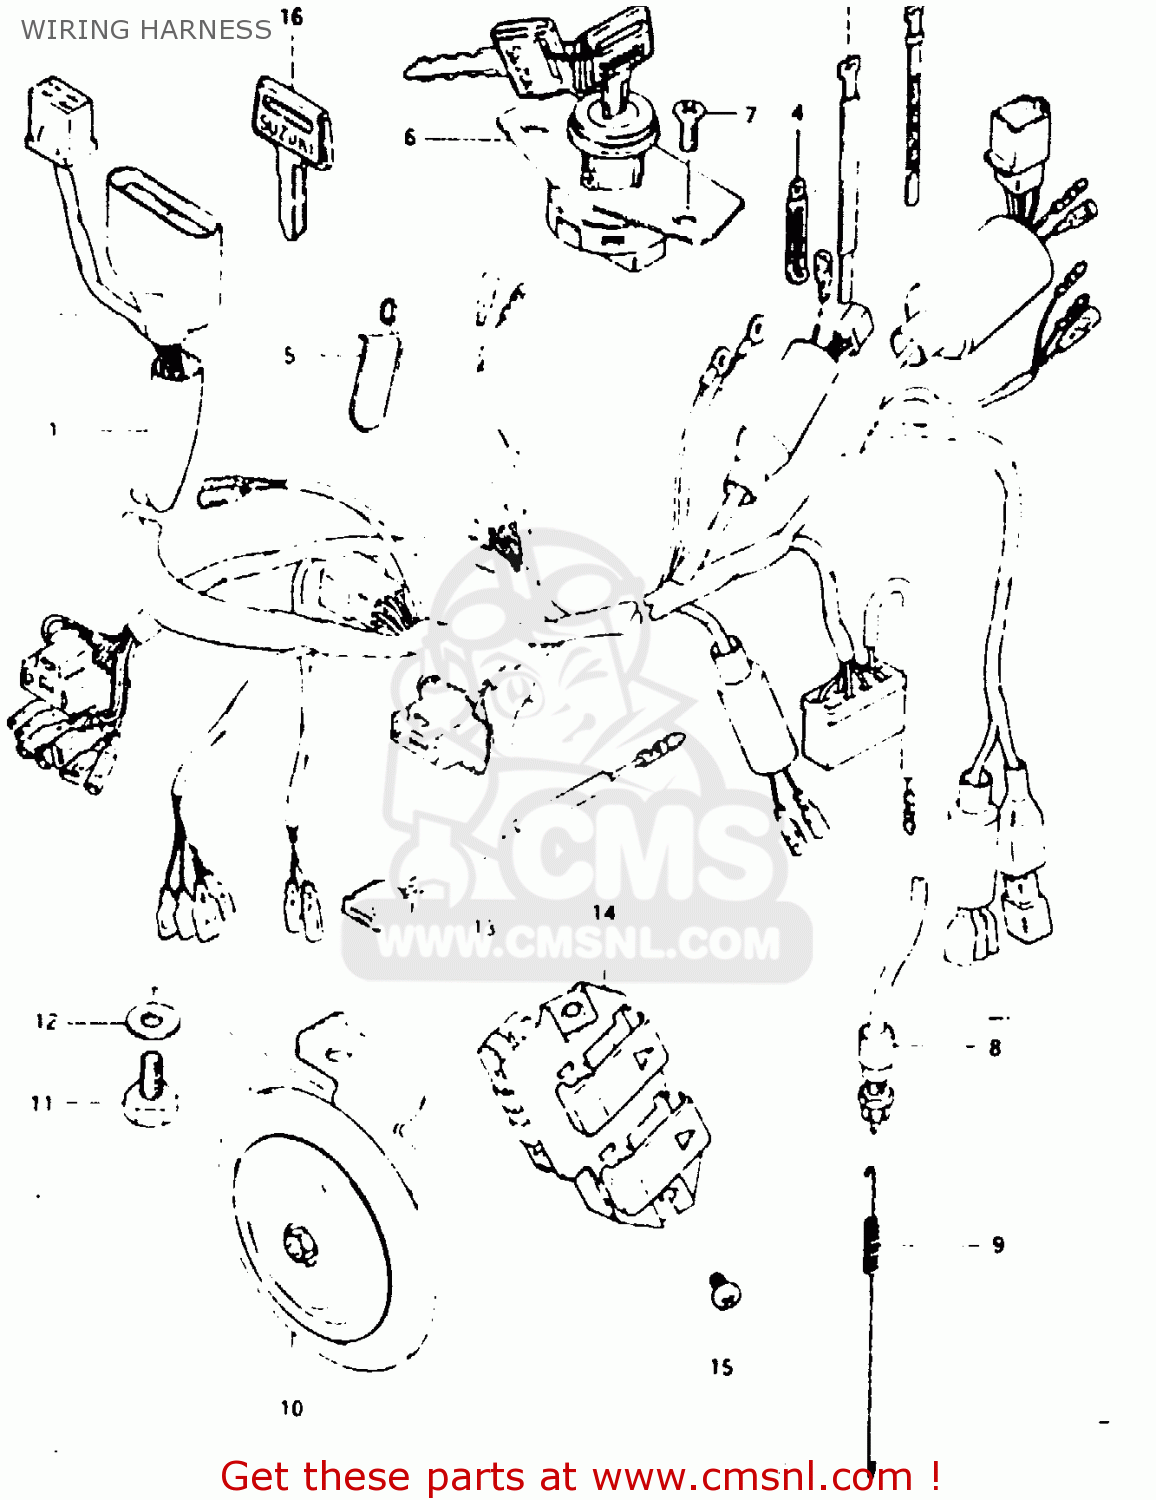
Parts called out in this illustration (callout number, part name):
1	WIRING HARNESS
2	CLAMP
3	CLAMP(L:80)
4	CLAMP
5	BOOT,WIRING HARNESS
6	SWITCH ASSY,IGNITION
7	SCREW
8	SWITCH ASSEMBLY,STOP LAMP
9	SPRING
10	HORN ASSY
11	BOLT 8X12
12	WASHER
13	WIRE
14	SWITCH ASSY,SIDE COVER,L
15	SCREW
16	KEY,BLANK
